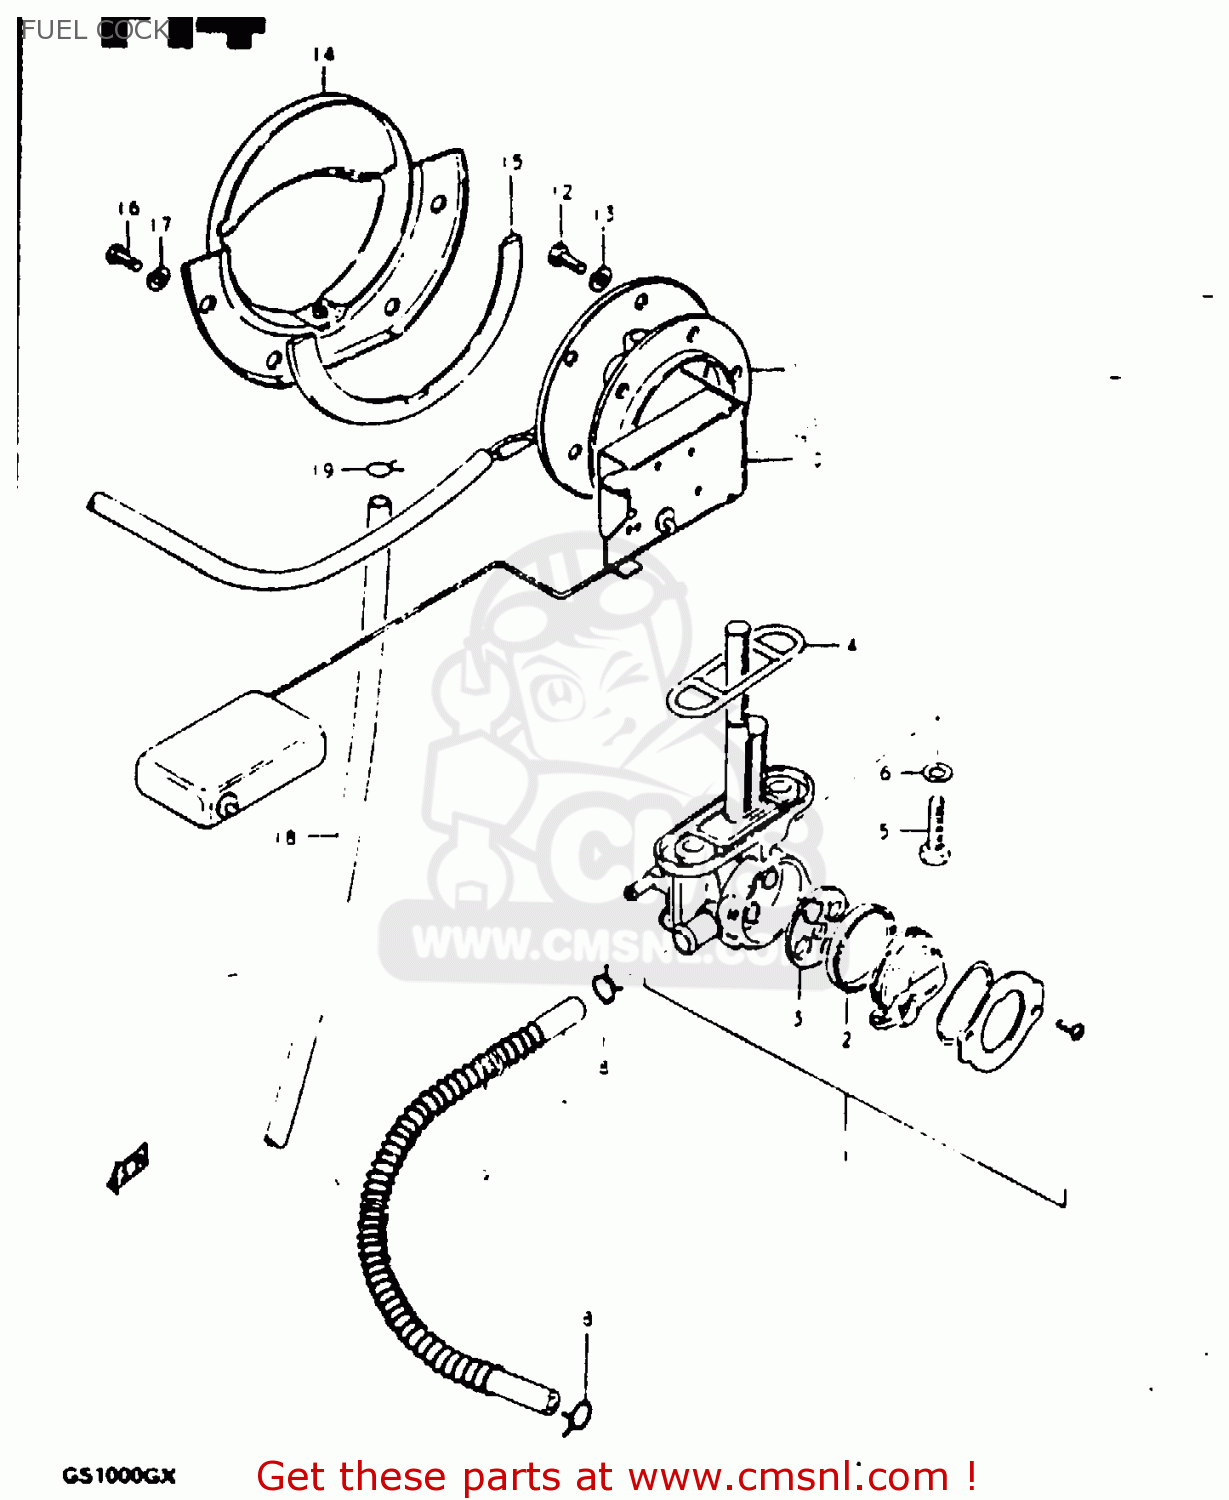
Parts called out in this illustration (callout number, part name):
1	COCK ASSY,FUEL
2	V SEAL,FUEL COCK
3	GASKET (NAS)
4	GASKET, FUEL COCK (NAS)
5	BOLT(6X20)
6	GASKET
7	HOSE
8	CLIP
9	SPRING
10	GAUGE ASSEMBLY,FUEL LEVEL
11	GASKET,FUEL LEVEL GAUGE (NAS)
12	BOLT
13	LOCK WASHER
14	PLATE,FUEL DRAIN
15	GASKET,FUEL DRAIN PLATE (NAS)
16	SCREW
17	LOCK WASHER
18	HOSE,FUEL
19	CLIP
